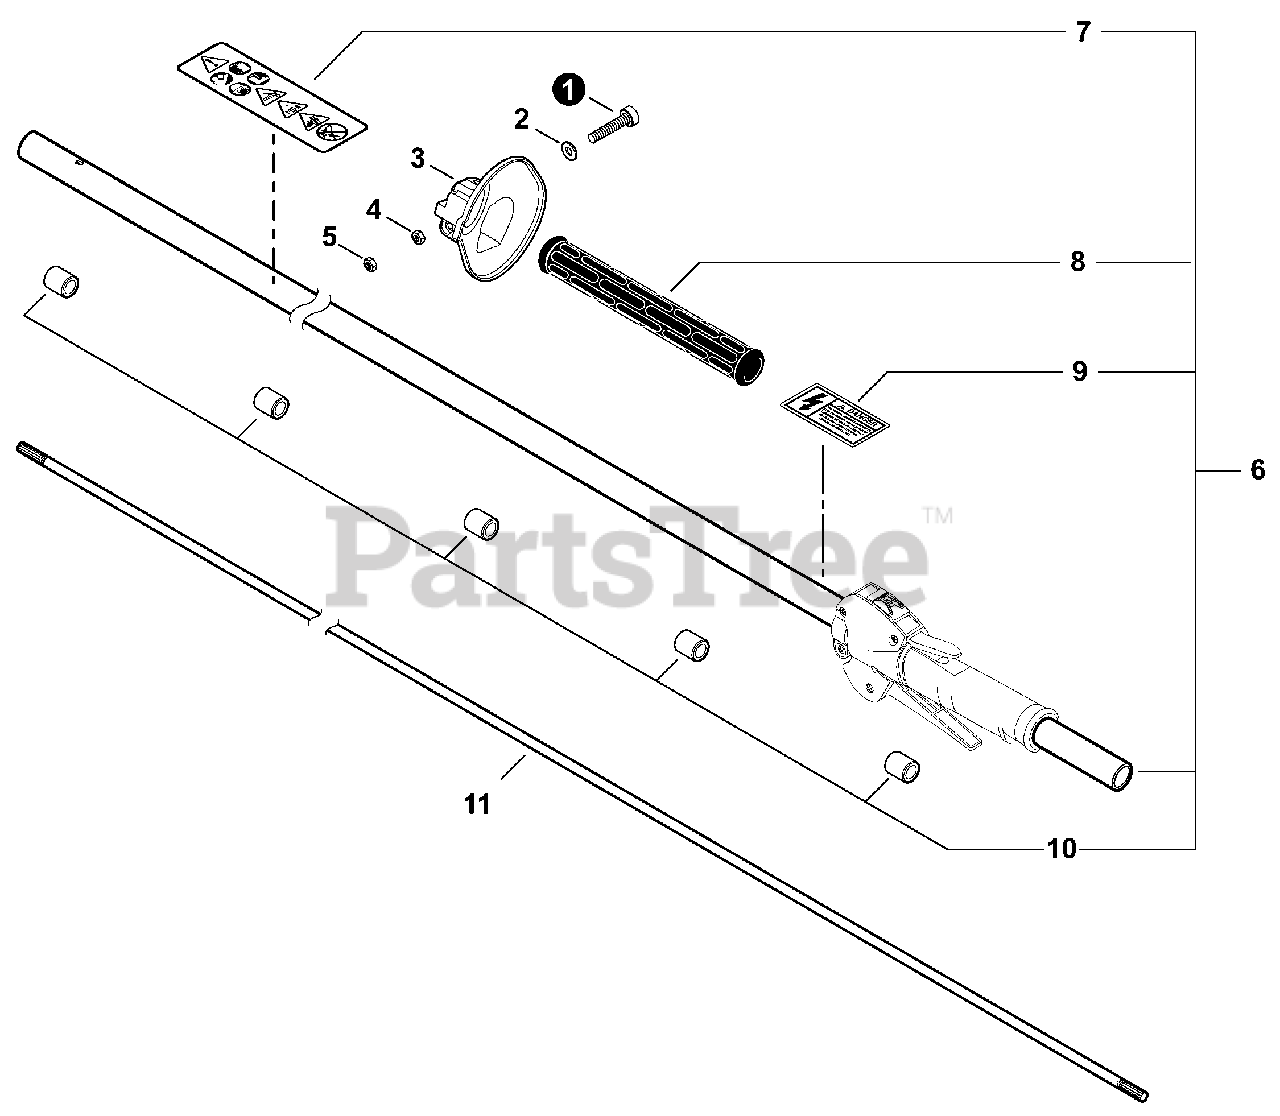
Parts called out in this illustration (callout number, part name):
1	SCREW - 5×35
2	WASHER 5.5×12×0.8
3	GUARD, HAND
4	NUT M5
5	NUT, LOCK M5
6	MAIN PIPE ASSY WITH GRIP
7	LABEL, CAUTION
8	GRIP, FRONT
9	LABEL, HIGH VOLTAGE
10	BUSHING
11	MAINSHAFT
